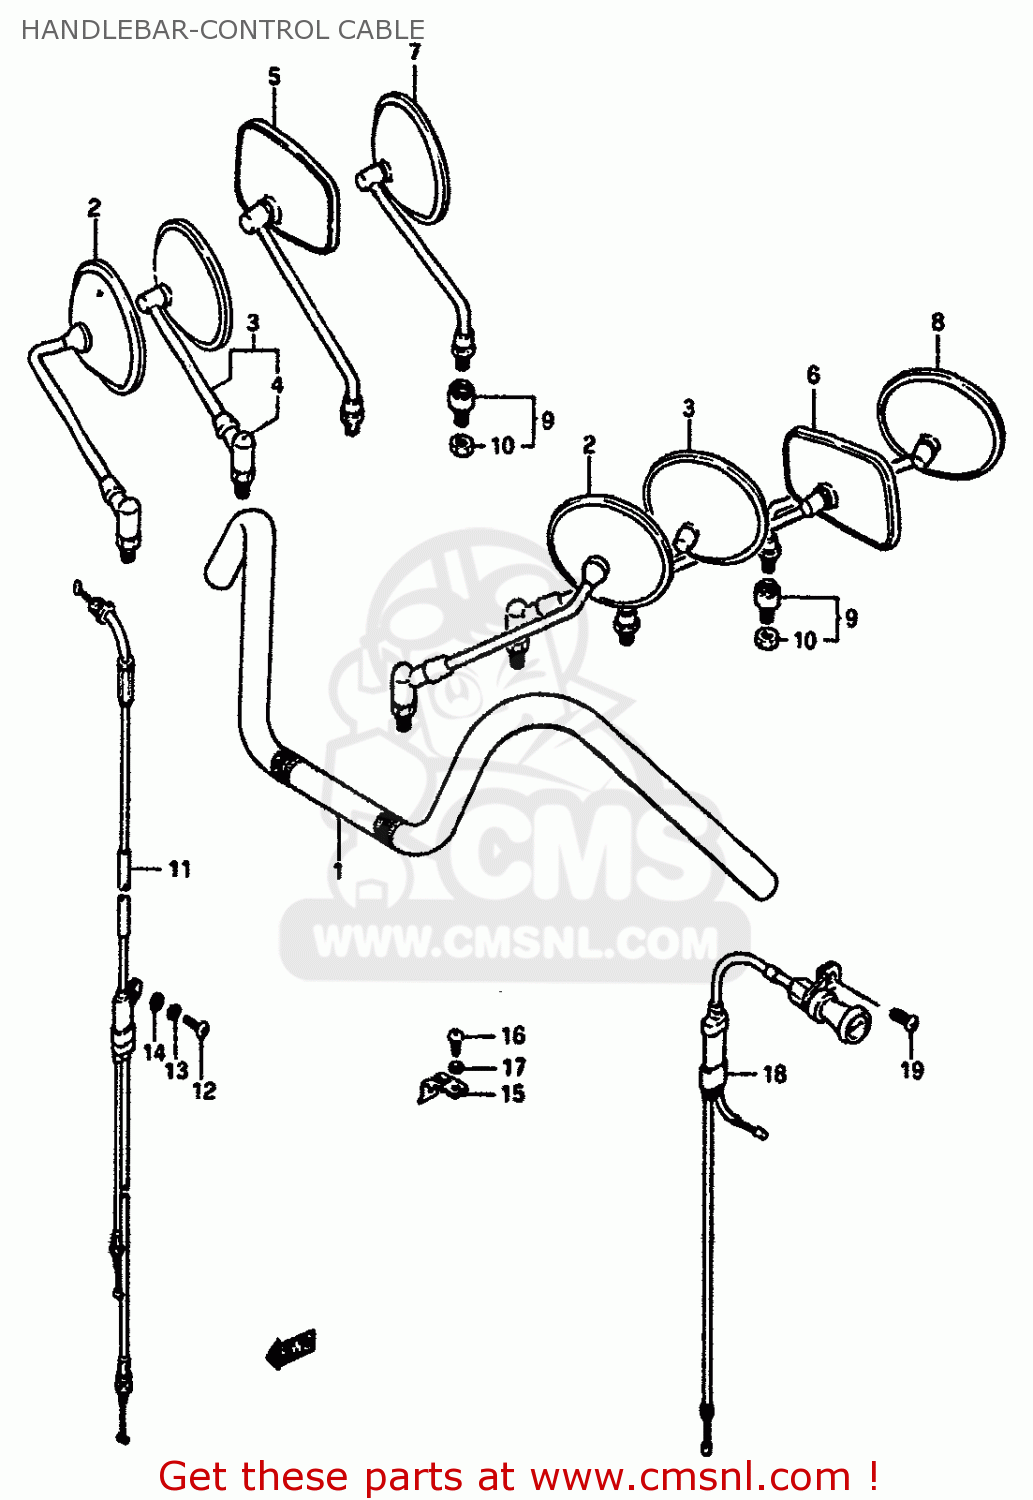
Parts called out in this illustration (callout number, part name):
1	HANDLEBAR
2	MIRROR, REAR VIEW RH
3	MIRROR ASSY,RH
4	CAP
5	MIRROR ASSY,RR VIEW,R
6	MIRROR ASSY,RR VIEW,L
7	MIRROR ASSY,REAR VIEW RH
8	MIRROR ASSY,REAR VIEW LH
9	CUSHION,REAR VIEW MIRROR
10	NUT
11	CABLE ASSEMBLY,THROTTLE
12	SCREW
13	LOCK WASHER
14	WASHER
15	CLAMP,THROTTLE CABLE
16	SCREW
17	LOCK WASHER
18	CABLE ASSEMBLY,STARTER
19	SCREW
